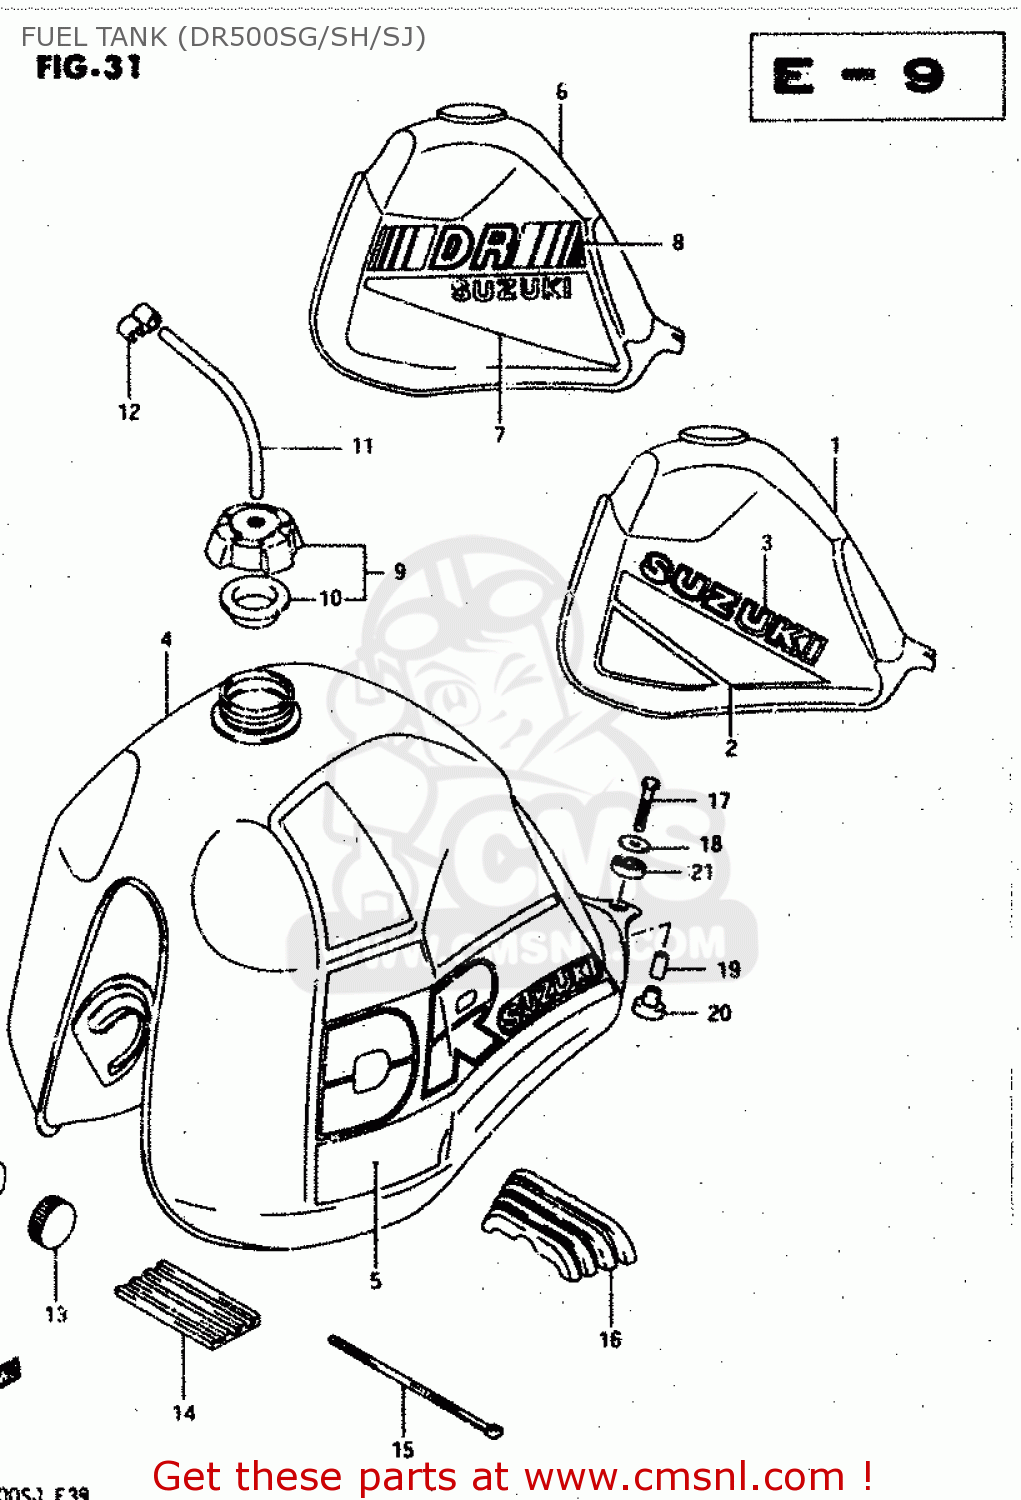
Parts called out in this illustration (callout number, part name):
1	TANK ASSY, FUEL (RED)
2	TAPE SET, FUEL TANK
3	EMBLEM,FUEL TANK
4	TANK ASSY, (BLUE)
5	TAPE SET, FUEL TANK
6	TANK ASSY, FUEL (BLUE)
7	TAPE SET, FUEL TANK
8	EMBLEM SET, FUEL TANK
9	CAP SET,FUEL TANK
10	GASKET,FUEL TANK CAP (NAS)
11	HOSE (L:240ARROW RIGHT200)
12	CLAMP,FUEL TANK BREATHER HOSE
13	CUSHION
14	CUSHION,FUEL TANK UPR FR
15	CLAMP
16	CUSHION,FUEL TANK RR
17	BOLT
18	WASHER (6.5X24X1.6)
19	SPACER
20	CUSHION
21	CUSHION
